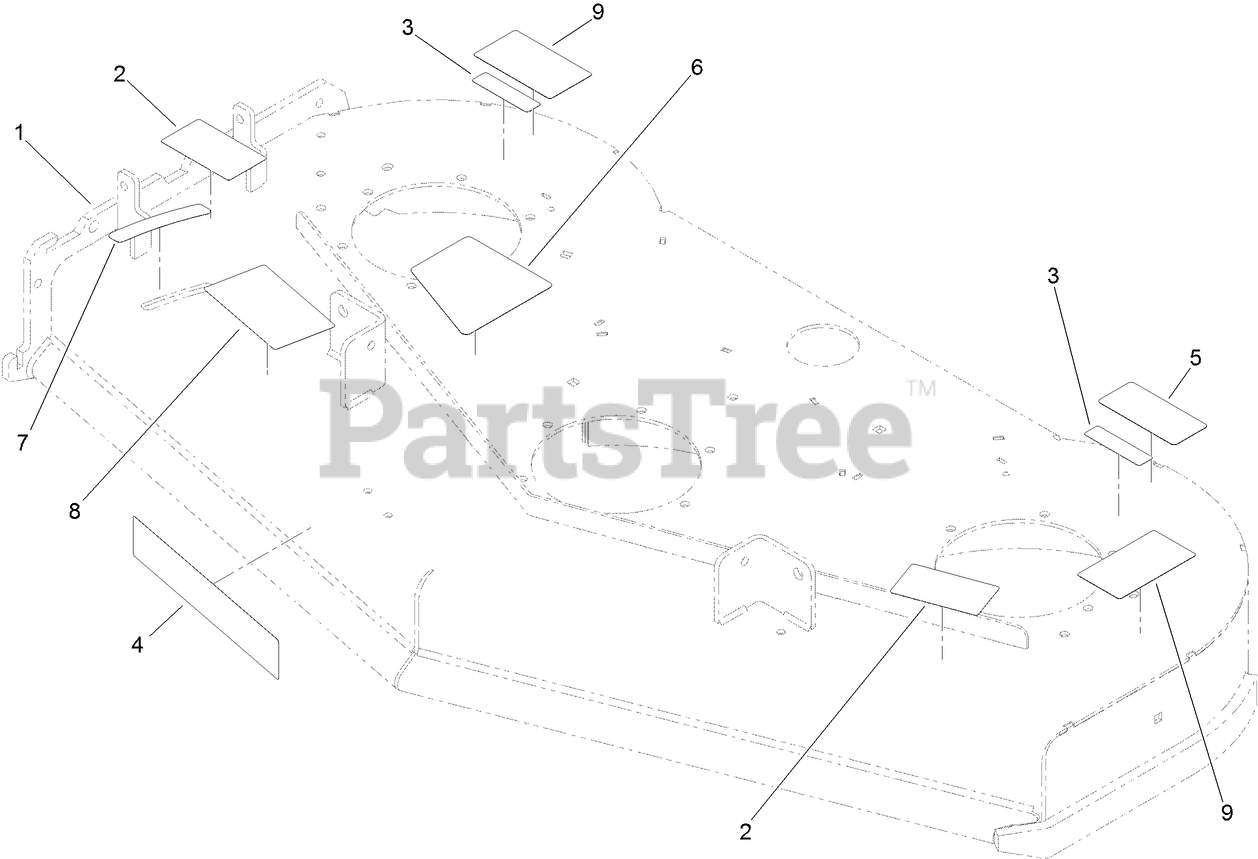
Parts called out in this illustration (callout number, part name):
1	DECK ASM
2	DECAL-DANGER
3	DECAL-DANGER
5	DECAL-TORQUE, BLADE BOLT
6	DECAL-BELT TENSION, CE
7	DECAL-SETTING, BAFFLE
8	DECAL-ADJUSTMENT, BAFFLE
9	DECAL-DANGER, ROTATING PARTS
